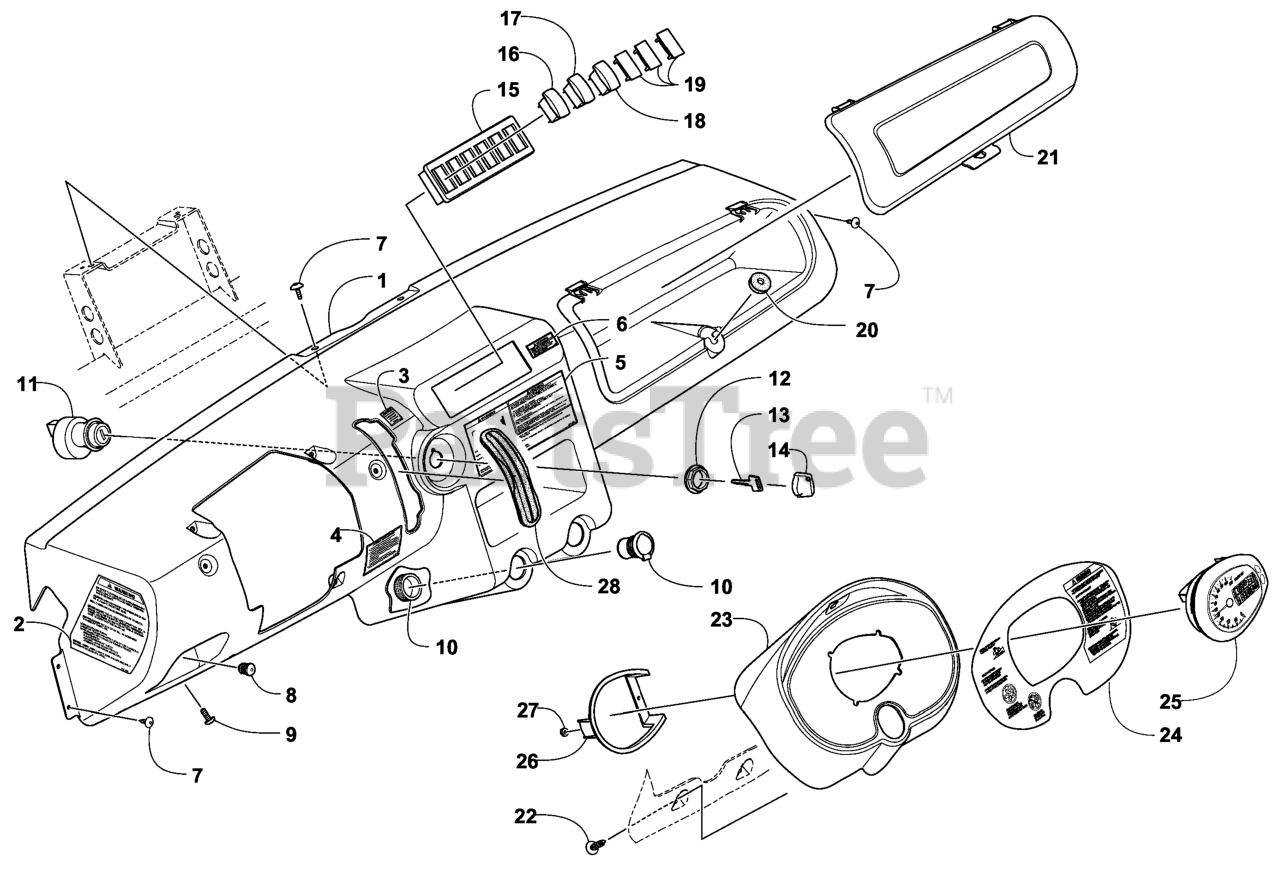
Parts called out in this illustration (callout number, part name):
1	PANEL-DASH, NON TILT/DASH
2	DECAL-WARNING, TIRE PRESS
3	DECAL-CAUTION, ENGINE RPM
4	DECAL-STARTING INSTRUCTIO
5	DECAL-WARNING, DASH CENTE
6	DECAL-WARNING, DIFFERENTI
7	SCREW-TSTRH, SELFTAP
8	PLUG-TUBE
10	OUTLET-12V DC
11	SWITCH-IGNITION, START
13	KEY-BLANK
14	COVER-KEY
15	PANEL-SWITCH MOUNT
16	SWITCH-LIGHTS
18	SWITCH-REVERSE, OVERRIDE
19	PLUG-SWITCH HOLE
20	GROMMET-LATCH, GLOVE BOX
21	COVER-GLOVE BOX
22	SCREW-SELF TAPPING
23	POD-INSTRUMENT
24	DECAL-WARNING, DASH
26	CLAMP-PLASTIC
28	KIT-SHIFT BOOT
